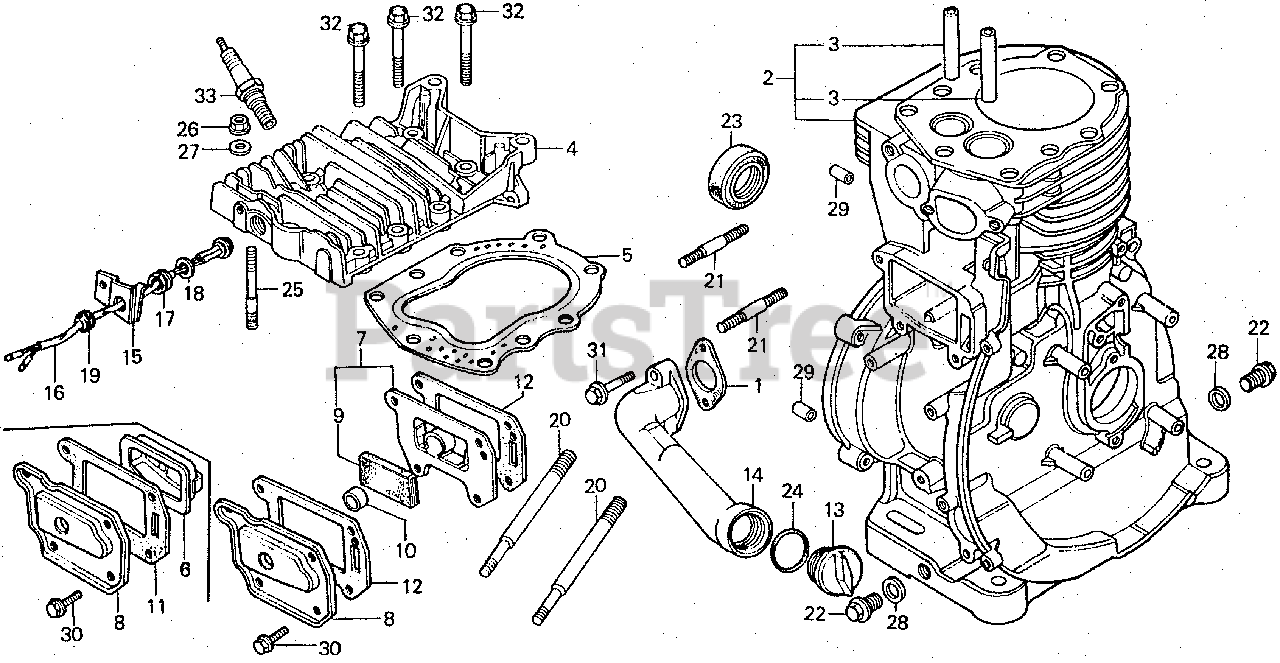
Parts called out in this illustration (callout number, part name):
1	GASKET, OIL PAN
2	CYLINDER (CRANKSHAFT P.T.O.) (NOT AVAILABLE)
2	CYLINDER (CRANKSHAFT P.T.O.)
3	GUIDE, VALVE
4	CYLINDER HEAD (NOT AVAILABLE)
5	GASKET, CYLINDER HEAD
6	CASE, BREATHER
7	CASE, BREATHER
8	COVER, TAPPET
9	FILTER, BREATHER
10	SEAL, BREATHER
11	GASKET, TAPPET COVER
12	GASKET, TAPPET COVER
13	CAP, OIL (YELLOW)
20	BOLT, STUD (8X110)
20	BOLT, STUD (8X104)
21	BOLT, STUD (8X35)
22	BOLT, DRAIN PLUG (12X15)
22	BOLT, DRAIN PLUG
23	OIL SEAL (30X46X8)
24	O-RING (26X2.7)
25	BOLT, STUD (10X70)
25	BOLT, STUD (10X60)
25	BOLT, STUD (10X40)
26	NUT, FLANGE (10MM)
27	WASHER, PLAIN (10MM)
28	WASHER, DRAIN PLUG (12MM)
29	PIN, DOWEL (8X14)
30	BOLT, FLANGE (6X12)
31	BOLT, FLANGE (6X25)
32	BOLT, FLANGE (10X55)
33	SPARK PLUG (BPR-4HS-10) (NGK)
33	SPARK PLUG (BPR4HS-10) (NGK)
33	SPARK PLUG (W14FPR-UL10)
